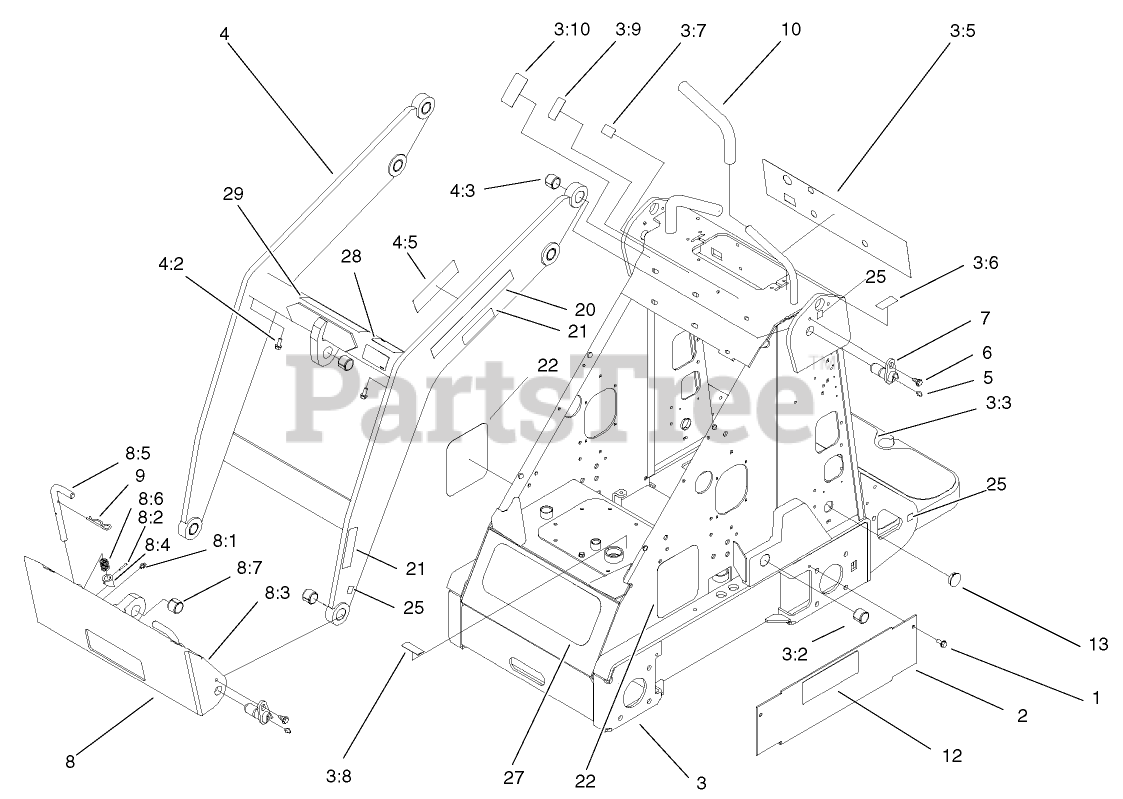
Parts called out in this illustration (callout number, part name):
1	SCREW-HWHTF
2	COVER-HOSE
3	FRAME ASM
3:2	BUSHING-TENSION
3:3	TREAD-FOOT
3:5	DECAL-PANEL, CONTROL
3:6	DECAL-THROTTLE
3:7	DECAL-LIMITER, SPEED
3:8	DECAL-OIL, HYD
3:9	DECAL-SELECTOR
3:10	DECAL-POWER, AUXILIARY
4	LOADER ASM
4:2	SCREW-HWHTF
4:3	BUSHING-TENSION
4:5	DECAL-DANGER
5	FITTING-GREASE
6	BOLT-SHOULDER
7	PIN-PIVOT
8	QUICK ATTACH ASM
8:1	FITTING-GREASE
8:2	PIN-SPECIAL
8:3	MOUNT-ATTACH, QUICK
8:4	CAM-ATTACH, QUICK
8:6	SPRING-COMPRESSION
8:7	BUSHING-TENSION
9	PIN-COTTER
10	GRIP-CUSHION
12	DECAL-4-PAW
13	PLUG-HOLE
20	DECAL-DINGO 320D
21	DECAL-WARNING, PINCH
22	DECAL-DINGO, SIDE
25	DECAL-POINT, LIFT
27	DECAL-DINGO, FRONT
28	DECAL-NO RIDER
29	DECAL-CAUTION
